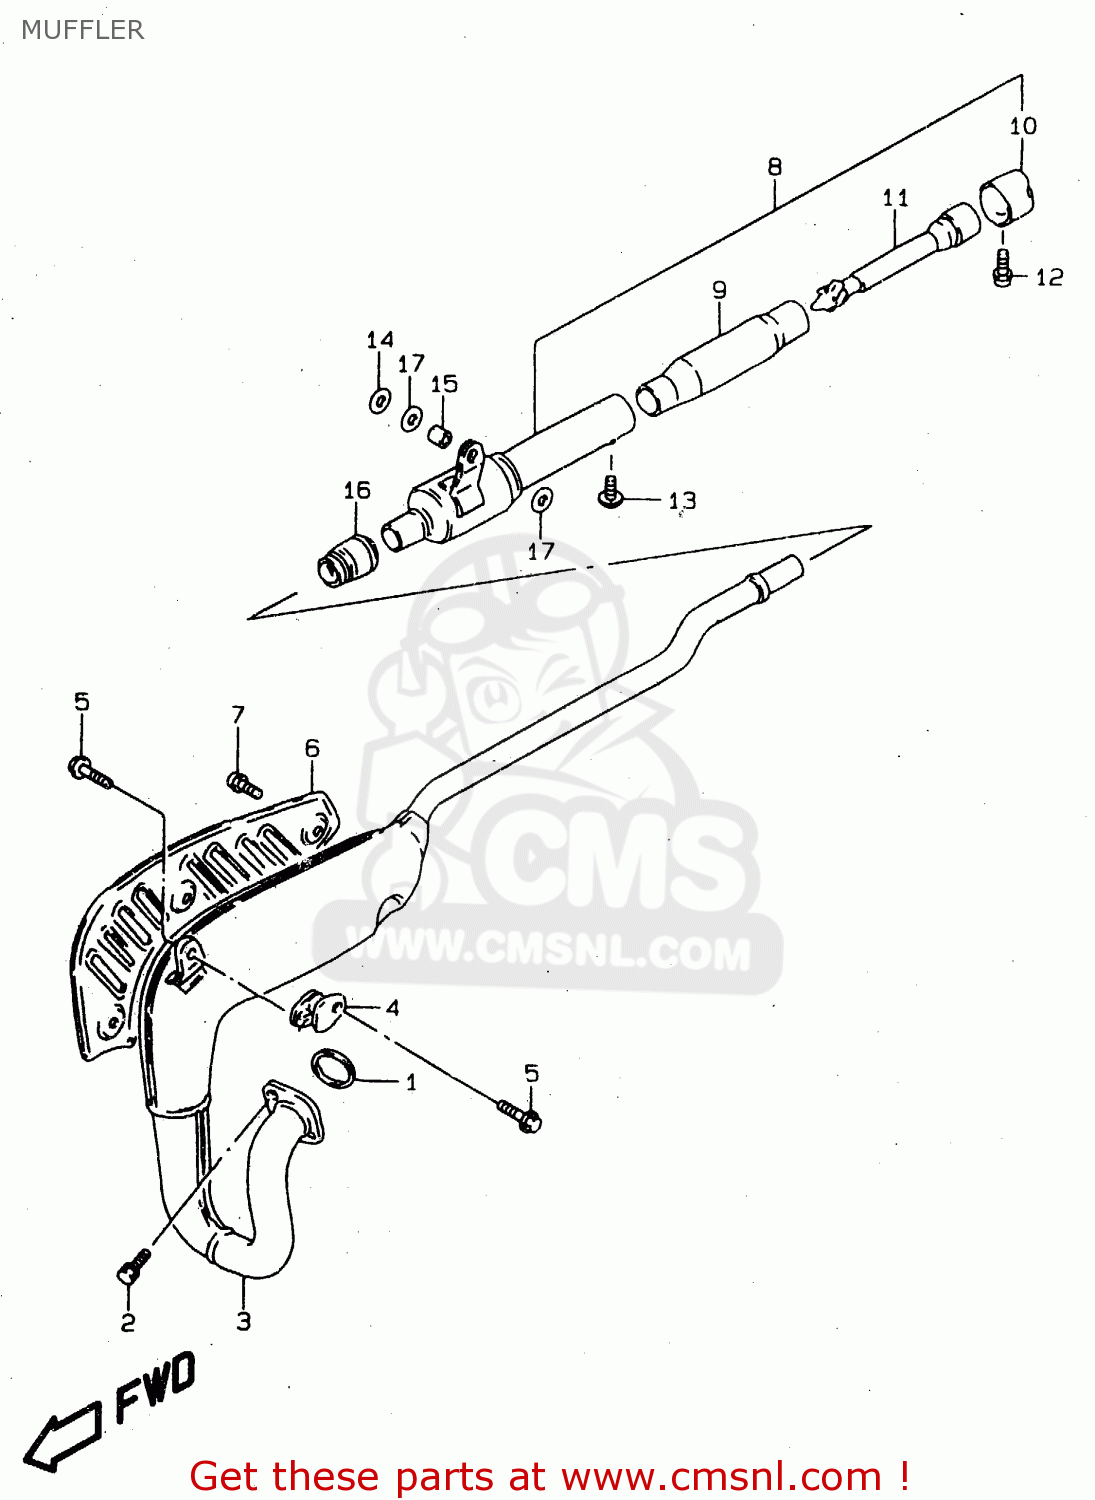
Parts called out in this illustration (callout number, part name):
1	GASKET,EXHAUST (NAS)
2	BOLT
3	BODY,MUFFLER 1ST
4	DAMPER,MUFFLER SUPPORT
5	BOLT
6	COVER,MUFFLER
7	SCREW
8	MUFFLER ASSY,2ND
9	SHELL,ARRESTER
10	CUTTER,MUFFLER TAIL
11	TUBE,CLEAN OUT
12	SCREW
13	SCREW
14	WASHER
15	SPACER,8.5X14X9
16	CONNECTOR,MUFFLER
17	CUSHION
